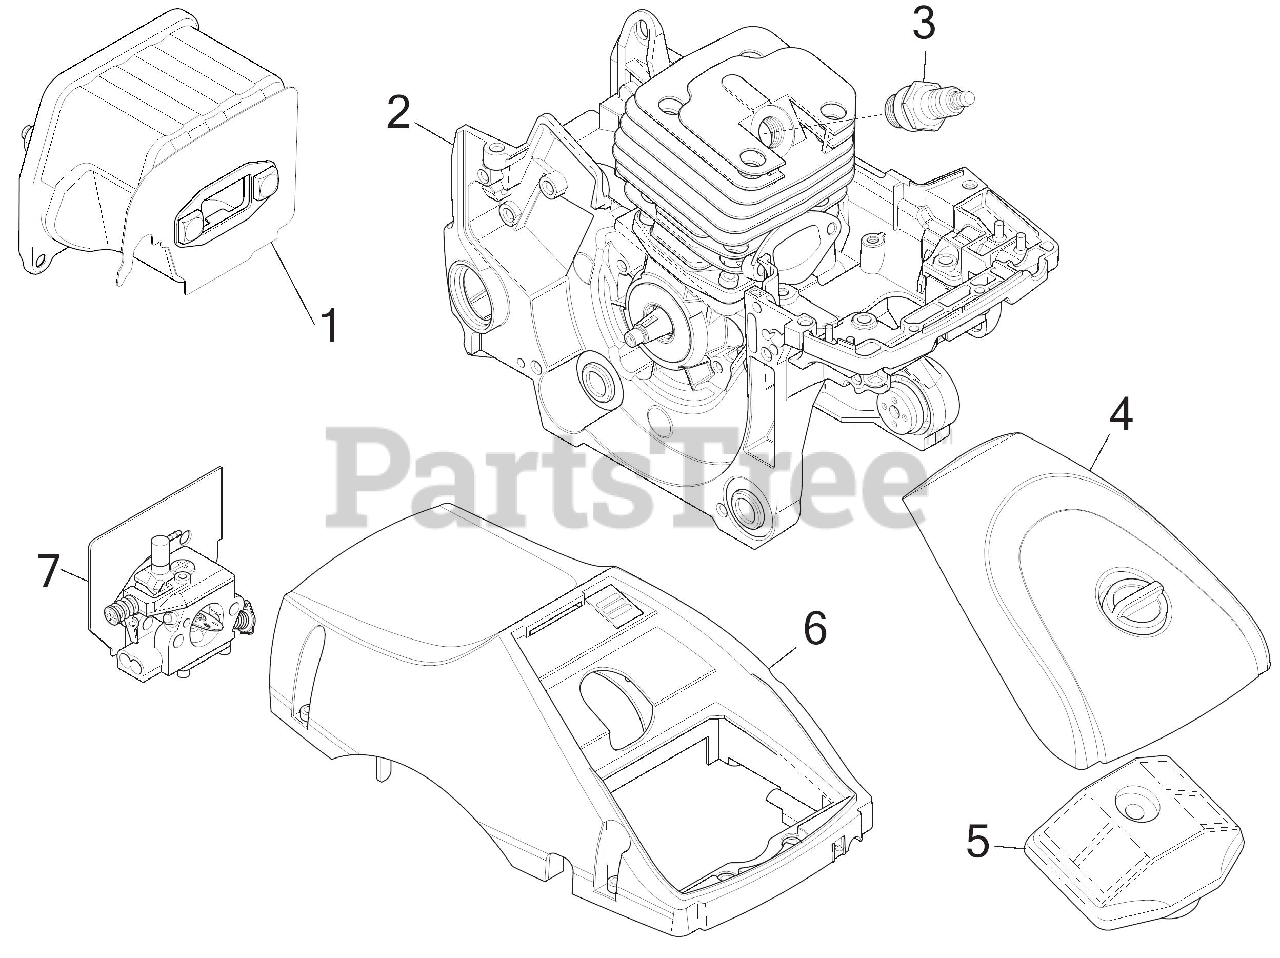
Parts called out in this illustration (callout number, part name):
1	MUFFLER ASSEMBLY:CHAINS
2	SHORTBLOCK 46CC
3	SPARK PLUG:L8RTF
4	COVER ASSEMBLY:AIR FLTR
5	AIR FILTER W/SEAL
6	COVER:CYL:CHAINSAW
7	CARBURATOR:CHAINSA
